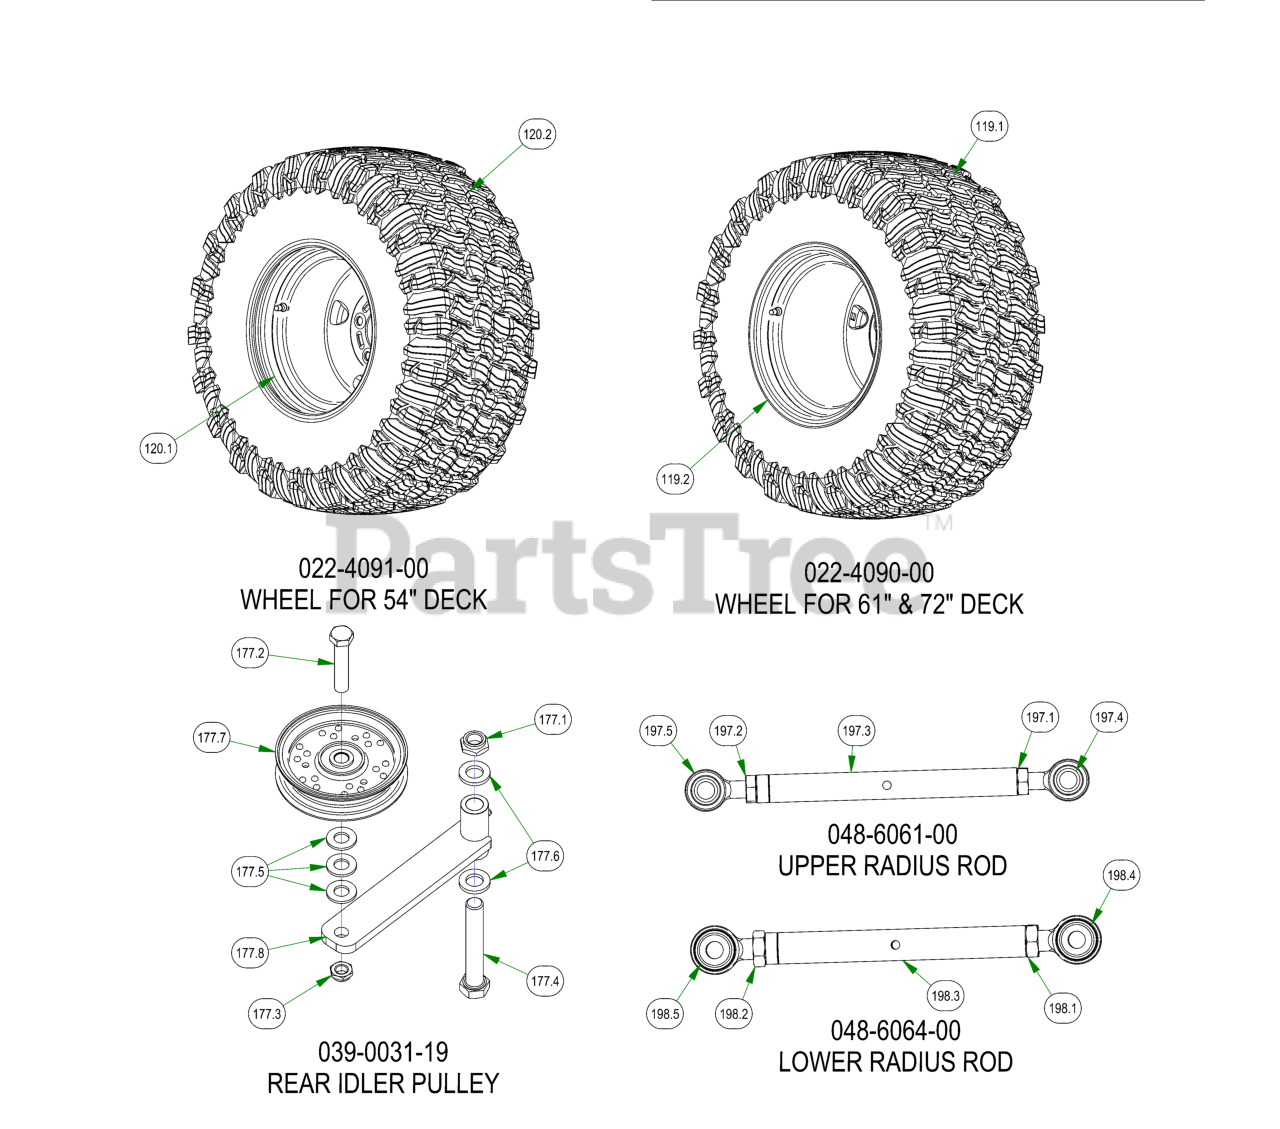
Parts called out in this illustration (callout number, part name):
119	2019 Assy-26x12-12 Reaper Turf -10.5" Rim
119.1	2019 26x12-12 Reaper Turf Tire
119.2	2019 10.5" Wheel
120	2019 Assy-26x12-12 Reaper Turf-8.5" Rim
120.1	12x8.5 Black Wheel
120.2	2019 26x12-12 Reaper Turf Tire
177	2019 Rogue Pump Idler Assy
177.1	5/8-11 NYLON INSERT JAM LOCKNUT ZINC
177.2	1/2-13 X 2-1/2 HEX CAP SCREW GR 5 ZINC
177.3	1/2-13 NYLON INSERT JAM LOCKNUT ZINC
177.4	5/8-11 X 4 HEX CAP SCREW (GR.8) ZINC YELLOW
177.5	1/2 SAE FLAT WASHER (1-1/16" OD) GR.8 ZINC YELLOW
177.6	.635 ID X 1.120 OD X .140 THICK FLAT WASHER NYLON
177.7	4 3/4 Idler Pulley - ABFI-76
177.8	2019 Vertical Suspension Drive Tensioner
197	2019 Suspension Radius Rod Assembly
197.1	5/8-11 HEX JAM NUT ZINC
197.2	NUT, 5/8-18LH
197.3	2019 Suspension Link Body
197.4	2019 RH 5/8" Heim
197.5	2019 LH 5/8" Heim
198	2019 Suspension Radius Rod Assembly
198.1	3/4-16 HEX JAM NUT ZINC
198.2	3/4-16 LH HEX JAM NUT ZINC
198.3	Rear Radius Rod, 3/4 Body
198.4	3/4-16 x 5/8 RH Heim
198.5	3/4-16 x 5/8 LH Heim
